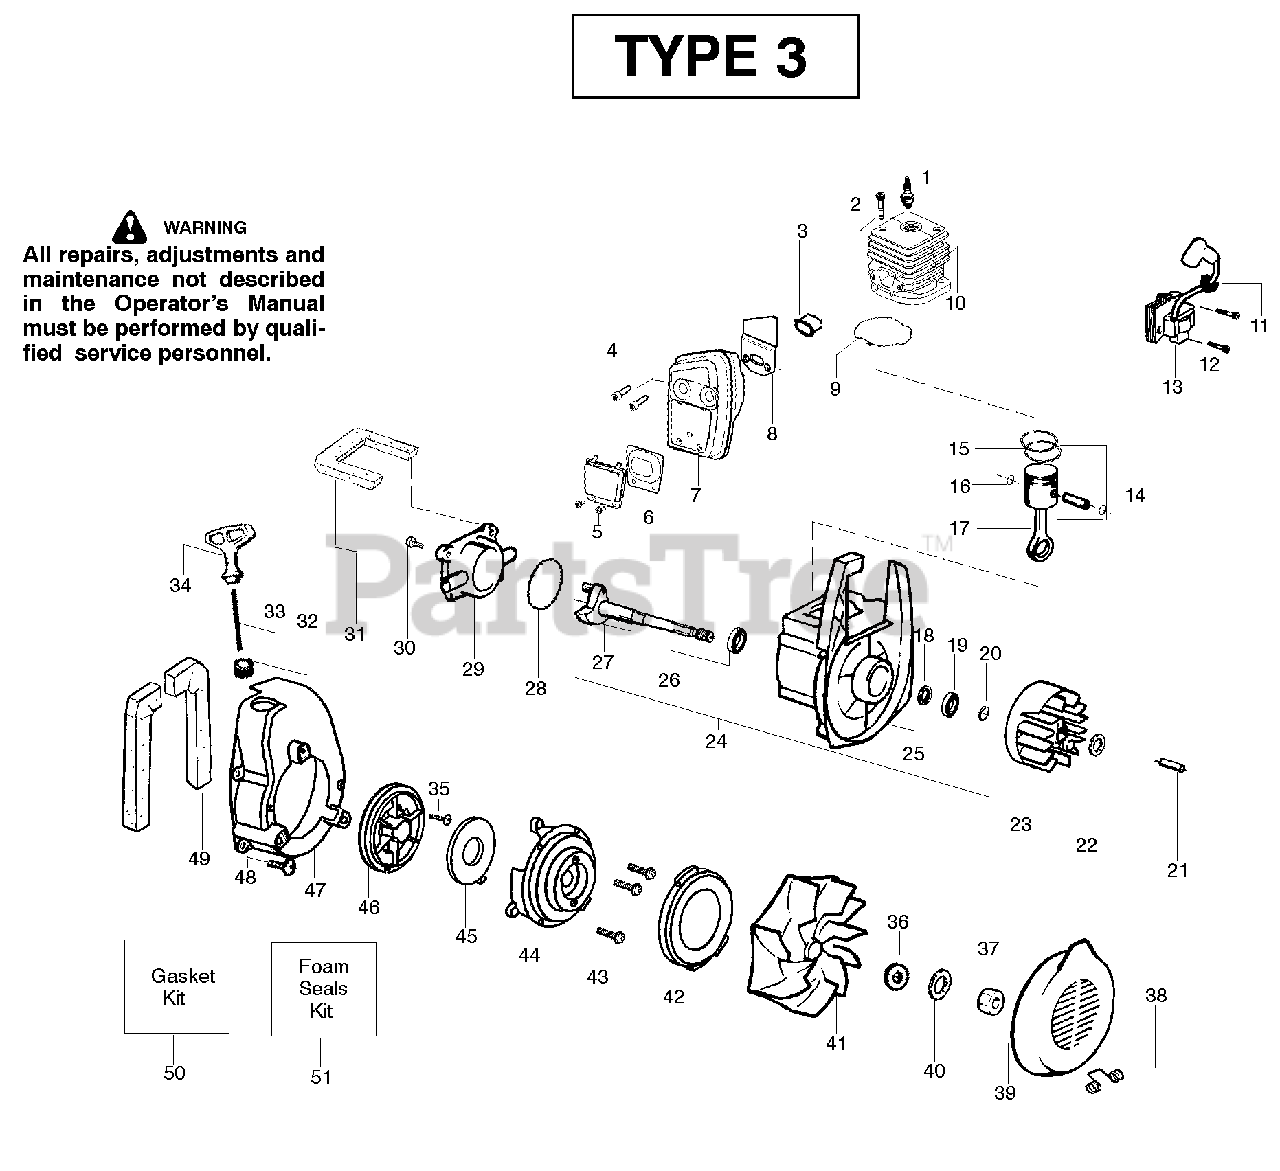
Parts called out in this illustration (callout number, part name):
1	Spark Plug (RCJ-6Y)
3	Insulator-Heat
4	Screw-Muffler-Internal
6	Kit-Spark Screen
7	Kit-Muffler
8	Gasket-Baffle (kit)
9	Gasket-Cylinder (kit)
10	Kit-Cylinder
11	Grommet-Ign. Module
12	Screw-Ignition Module
13	Ignition Module
14	Kit-Piston
15	Piston Ring
16	Retainer-Piston Pin
17	Assy-Connecting Rod
18	Seal-Crankcase
19	Bearing-Outer
20	Retainer Ring-C'shaft
21	Spacer-Flywheel
23	Assy-Flywheel
24	Assy-Crankcase/Crank shaft
25	Assy-Crankcase
26	Bearing-Inner
27	Assy-Crankshaft
28	O-ring-C/case (kit)
29	Cover-Crankcase
30	Screw
31	Foam-219mm (kit)
32	Eyelet-Flange
33	Kit-Rope
34	Handle-Starter
35	Screw-Rope
36	Washer-Belleville
38	Spring-Return Cover
39	Inlet Door
40	Washer-Flat
41	Assy-Impeller
42	Seal-Ring
44	Housing-Pulley
45	Spring-Starter
46	Kit-Starter Pulley
47	Fan Housing
48	Screw
49	Foam-182mm (kit)
50	Kit-Gasket
51	Kit-Foam Seals
